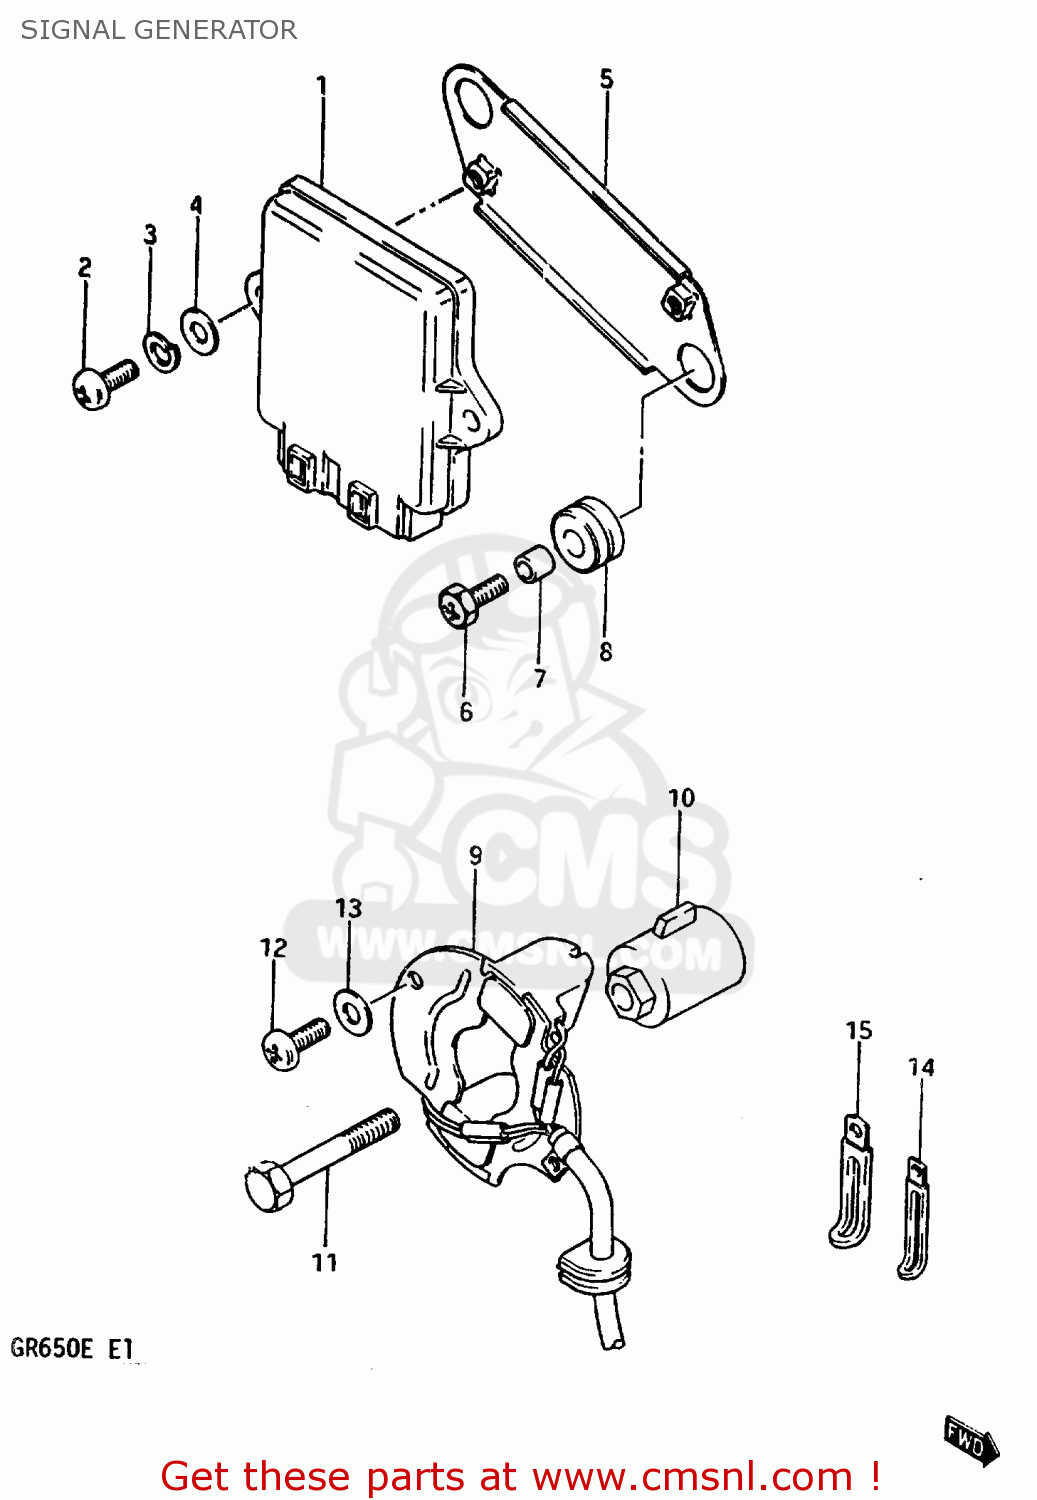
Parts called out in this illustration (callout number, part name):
1	IGNITER UNIT ASSEMBLY
2	SCREW
3	LOCK WASHER
4	WASHER
5	BRACKET,IGNITER
6	SCREW
7	SPACER(6.2X8.3X6.1)
8	CUSHION
9	SIGNAL GENERATOR ASSEMBLY
10	GOVERNOR ASSEMBLY
11	BOLT 8X50
12	SCREW(5X12)
13	WASHER
14	CLAMP L:35
15	CLAMP
